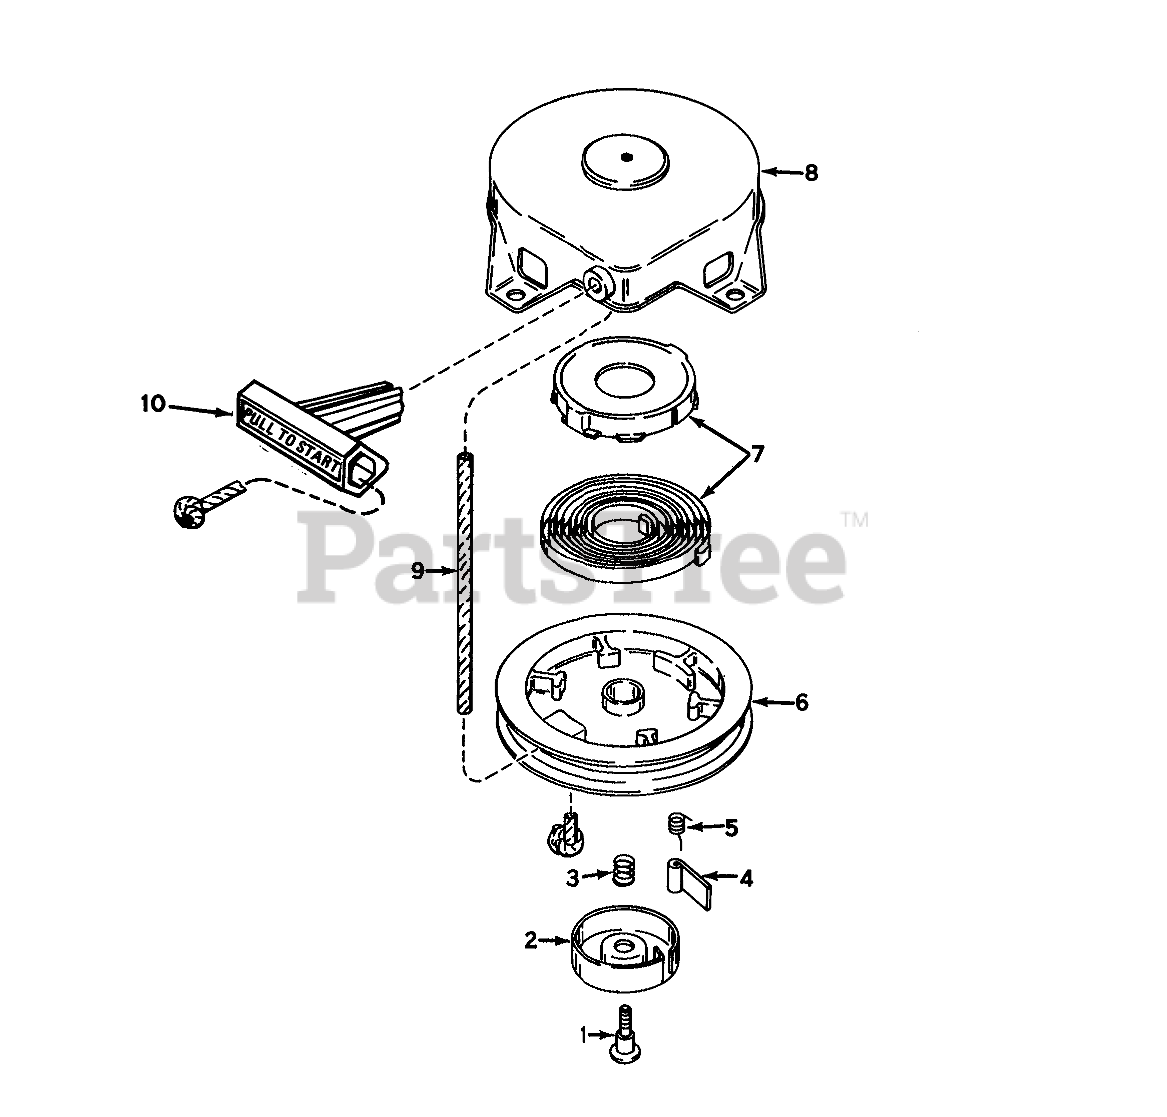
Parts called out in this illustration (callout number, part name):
2	Retainer
3	Spring-Brake
4	Dog-Starter
5	Spring-Dog
7	Spring & Keeper Assy
8	Housing-Starter
9	Rope-Starter (98 cut to length)
10	Handle-Starter
